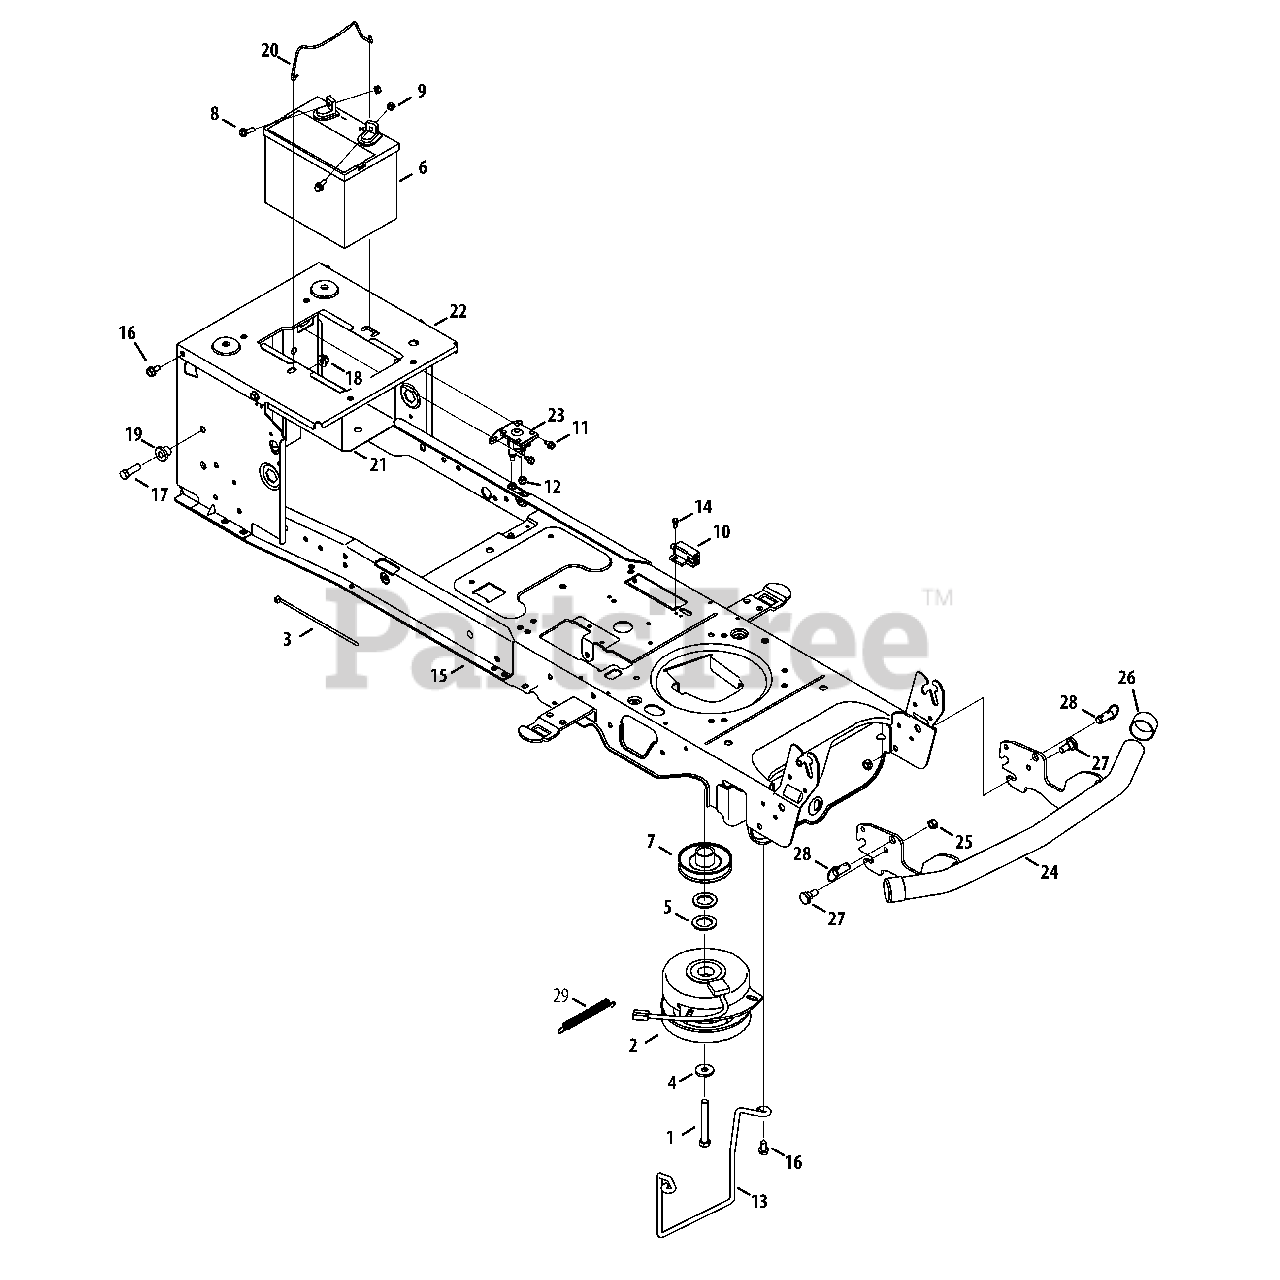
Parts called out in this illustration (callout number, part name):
1	Hex Screw, 7/16-20, 3.50, Gr5, Lock
2	Clutch, Electric PTO, 50"
2	Clutch Harness Wire 11.625"
3	Cable, Tie, 3/16 X .05 X 7.4
4	Washer, Flat, .450 x 1.25 x .164
5	Washer, Flat, 1.031 X1.620 X.095
7	Engine Pulley, Electric PTO
8	Hex Flange Screw, 1/4-20, .75, Gr5
9	Nut, Sems, 1/4-20
10	Switch, Interlock
11	Screw, Self-tapping, 1/4-20, 0.375
12	Nut, Flange Lock, 1/4-20, Nylon
13	Rod, Keeper
14	Screw, Shoulder, #10-32, .50
15	Frame Assembly, Lower
16	Screw, Self-tapping, 5/16-18, .750
17	Hex Screw, 3/8-16, 1.25, Gr5
18	Nut, Flange Lock, 3/8-16, Nylon
19	Spacer, Shoulder, .38 X 1.0 X .70
20	Rod, Battery
21	Tray, Battery
22	Bracket, Frame, Seat
23	Solenoid, 12V, 100 Amp, 4 term
24	Bumper Assembly, Universal
25	Hex Lock Nut, 3/8-16
26	Cap, Bumper
27	Bolt, Shoulder, .496 x .336, 3/8-16
28	Pin, Quick Release, 1/2 Dia x .50
29	Spring, Extn, .56 Dia X 5.52
